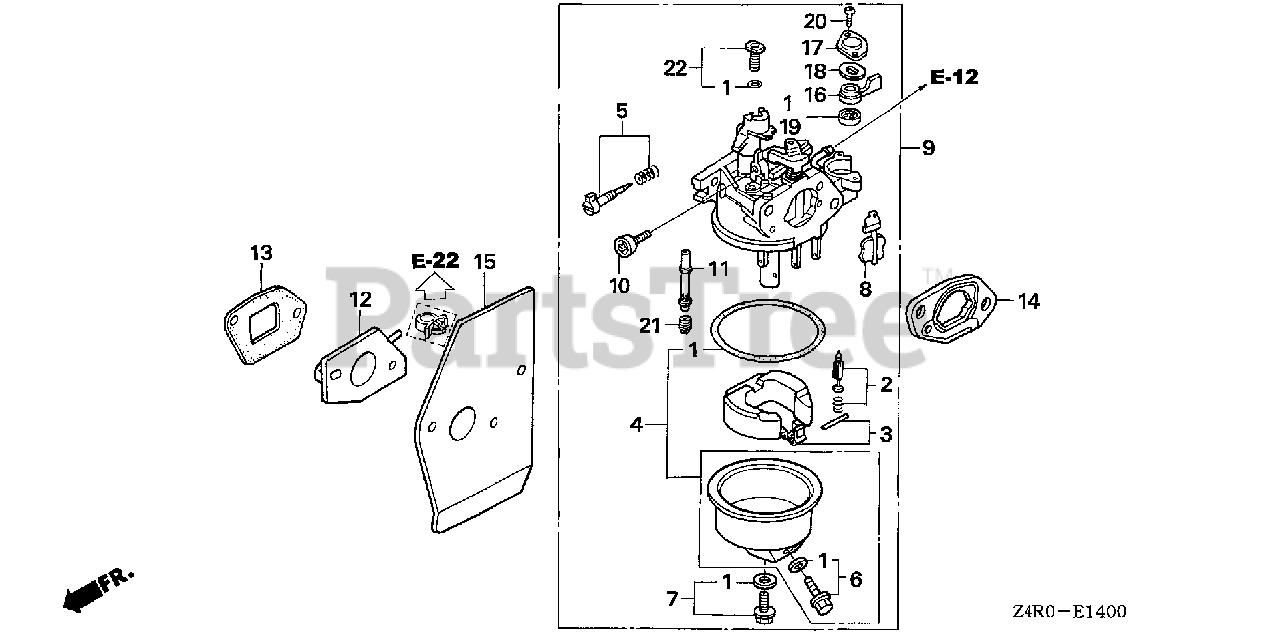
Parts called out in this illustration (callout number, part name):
1	GASKET SET
2	VALVE SET, FLOAT
4	CHAMBER SET, FLOAT
5	SCREW SET, PILOT
6	SCREW SET, DRAIN
7	SCREW SET
9	CARBURETOR ASSY. (BE66C B)
10	SCREW, THROTTLE STOP
11	NOZZLE, MAIN
12	INSULATOR, CARBURETOR
13	GASKET, INSULATOR
14	SPACER, CARBURETOR
15	GASKET, CARBURETOR
16	LEVER, PETCOCK
17	PLATE, LEVER SETTING
18	SPRING, PETCOCK LEVER
19	GASKET, PETCOCK
20	SCREW, PAN (3X6)
21	JET, MAIN (#65)
21	JET, MAIN (#60)
21	JET, MAIN (#62)
22	JET SET, PILOT (#35)
